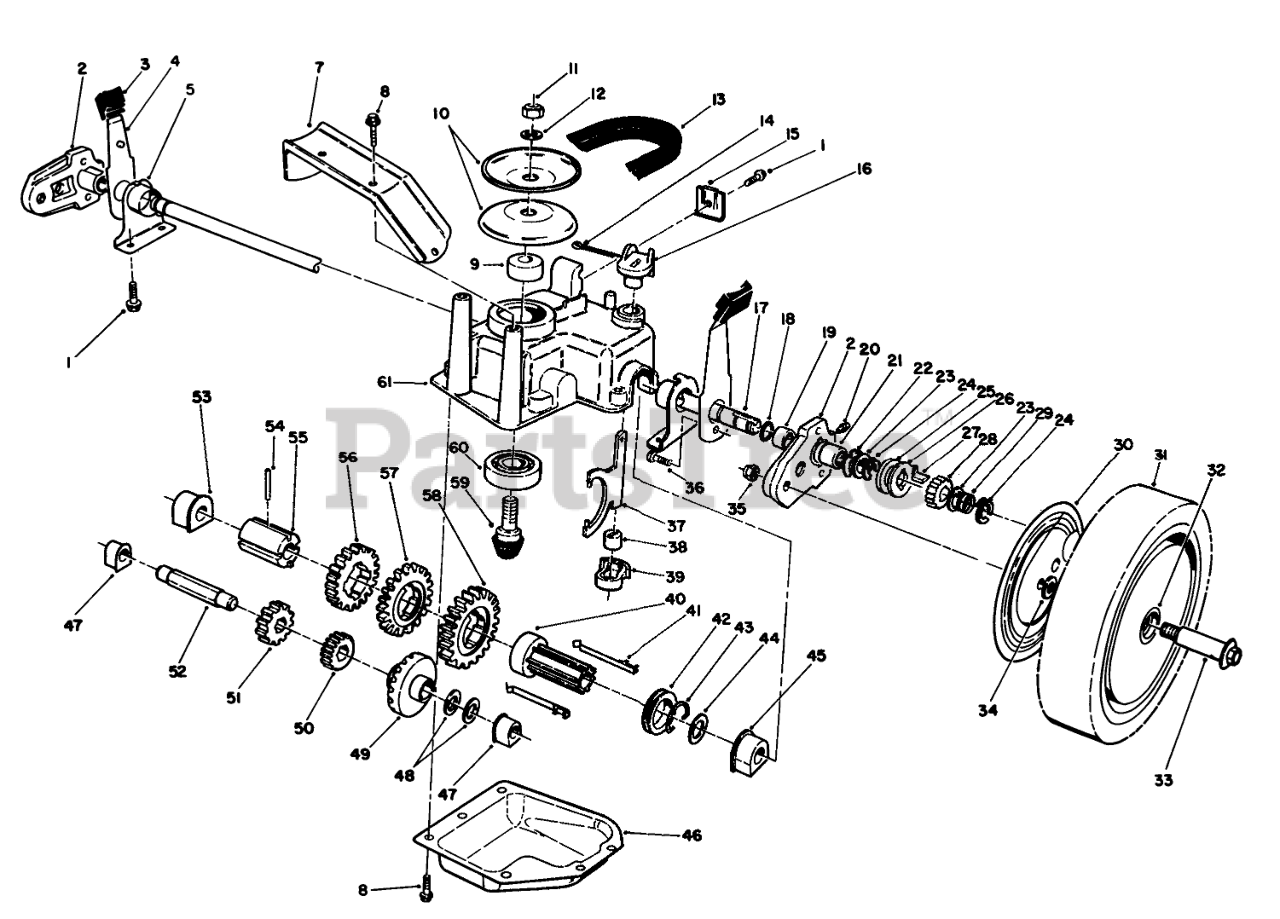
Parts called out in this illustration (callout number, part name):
1	SCREW-HWHTF
2	Pivot Arm Assembly (Incl. Ref. #19-21)
3	KNOB-ARM
4	SPRING ARM ASM
5	CAP-END
7	Bracket-BeltGuide
8	SCREW-HWHTF
9	SPACER
10	Pulley Half
11	NUT-HEX
12	WASHER-FLAT
13	V-BELT
14	PIN-COTTER
15	CABLE CLAMP
16	Lever-Shift
17	SHAFT-OUTPUT
18	O-RING
19	BUSHING
20	FITTING-GREASE
21	BEARING-ROLLER
22	WASHER-ARM, PIVOT
23	WASHER-THRUST, KEYED
24	RING-CLIP, LOCKING
25	RING-FRICTION
26	WASHER-CLUTCH
27	KEY-ROCKING, LH
28	GEAR-PINION
29	SPRING-COMPRESSION
30	WHEEL COVER
31	Wheel Tire & Gear Assy. (Incl. Ref. #32)
32	BUSHING
33	WHEEL BOLT
34	WASHER
35	Nut
36	SCREW-HSH, THREAD FORMING
37	YOKE-SHIFT
38	BUSHING-YOKE
39	RETAINER-FORK, SHIFT
40	Sleeve-Shift Key
41	SHIFT KEY
42	SHIFT COLLAR
43	CLIP-SPRING
44	WASHER-PLAIN
45	BUSHING-OUTPUT
46	Cover-Gearcase
47	BUSHING
48	WASHER-THRUST
49	Gear-Bevel
50	PINION-20T
51	PINION-25T
52	SHAFT-INTERMEDIATE
53	BUSHING
54	PIN-SPRING
55	SLEEVE-GEAR
56	GEAR-39T
57	GEAR-44T
58	GEAR-49T
59	Gear-Pinion
60	BEARING-BALL
61	CASE-GEAR, UPPER
